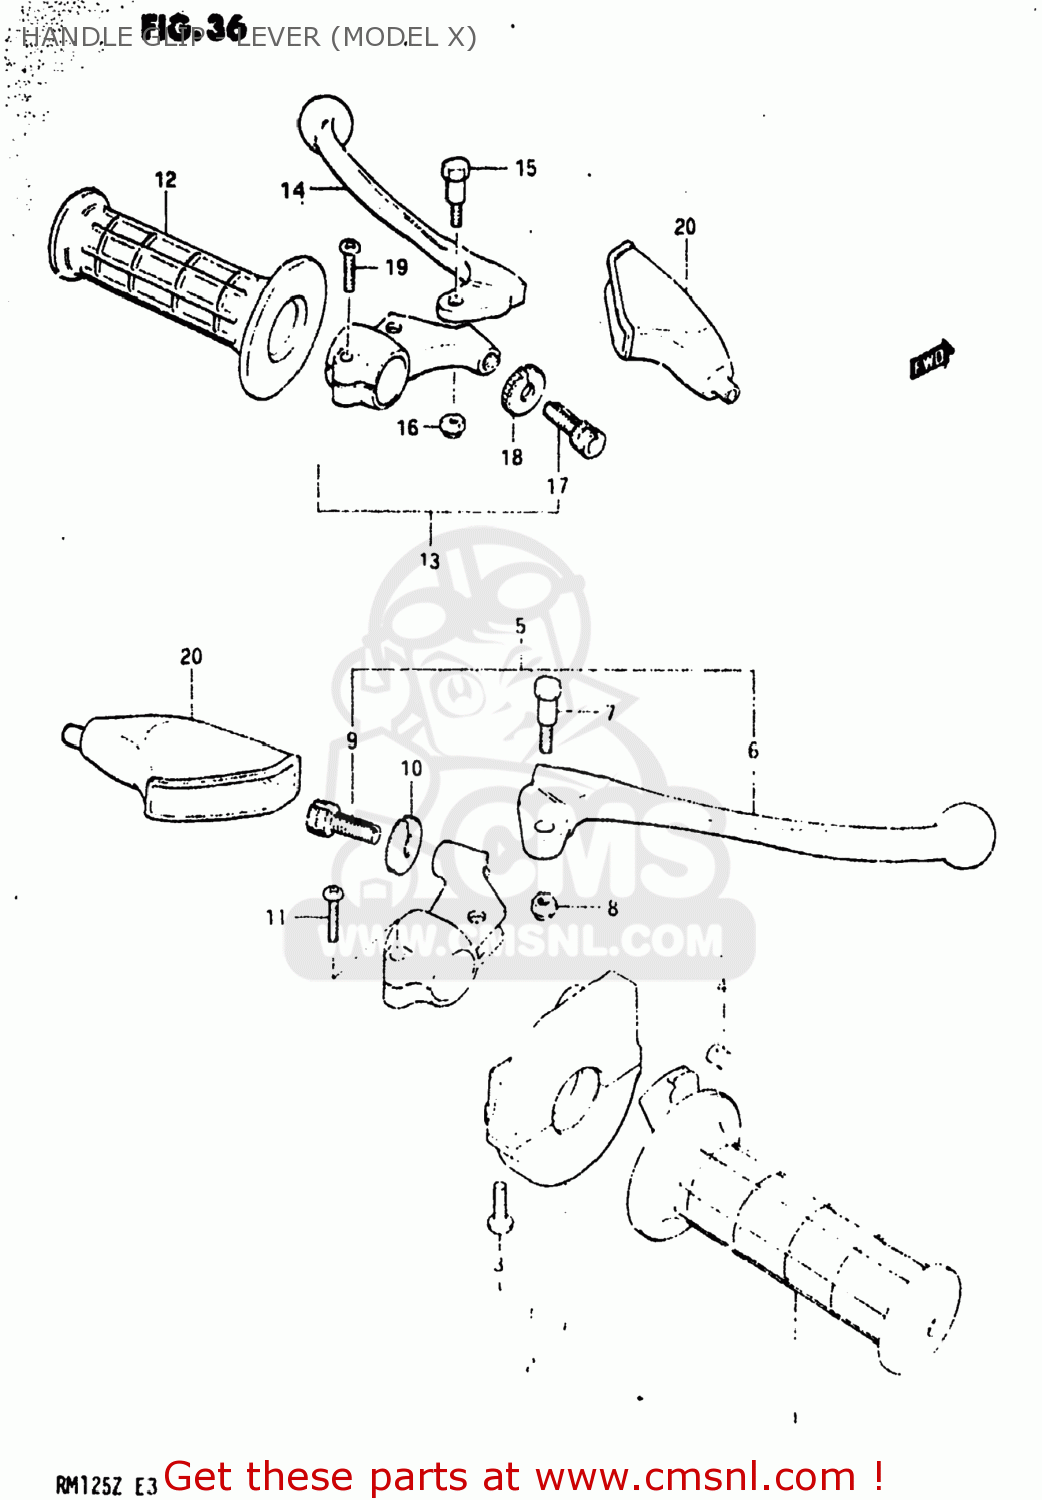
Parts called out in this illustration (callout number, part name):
1	GRIP,THROTTLE
2	CASE ASSEMBLY,THROTTLE
3	SCREW
4	PIECE,THROTTLE END
5	LEVER ASSEMBLY,BRAKE
6	LEVER,BRAKE
7	BOLT,LEVER
8	NUT 6MM
9	ADJUSTER,CABLE
10	NUT,CABLE ADJUSTER
11	SCREW
12	GRIP,LEFT
13	LEVER ASSEMBLY,CLUTCH
14	LEVER,CLUTCH
15	BOLT,LEVER
16	NUT 6MM
17	ADJUSTER,CABLE
18	NUT,CABLE ADJUSTER
19	SCREW
20	COVER,CLUTCH LEVER
